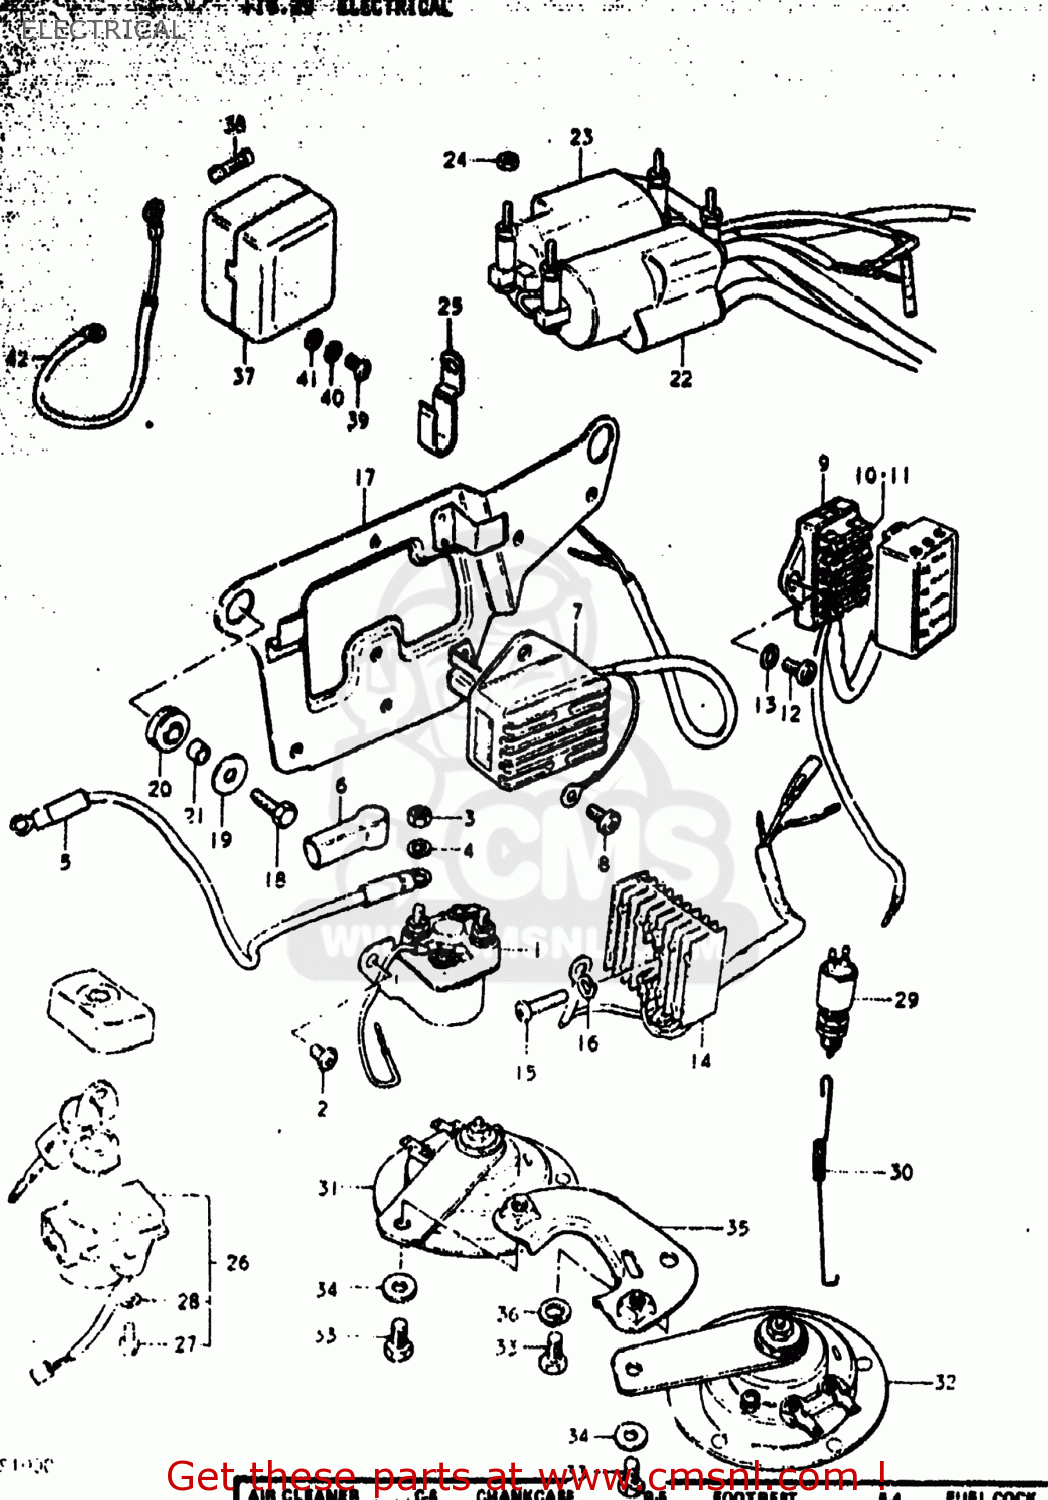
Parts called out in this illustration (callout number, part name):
1	RELAY ASSY,STARTING MOTOR
2	SCREW
3	NUT 6MM
4	LOCK WASHER
5	WIRE,STARTER MOTOR LEAD
6	CAP,STARTER RELAY
7	REGULATOR ASSY,VOLTAGE
8	SCREW
9	BOX ASSEMBLY,FUSE
10	FUSE(10A)
11	FUSE(15A)
12	SCREW 6X12
13	WASHER 6MM
14	RECTIFIER ASSEMBLY
15	SCREW
16	LOCK WASHER
17	HOLDER COMP,ELECTRONIC PARTS
18	BOLT, UPPER
19	WASHER(6,5X22X1.6)
20	CUSHION
21	SPACER(6.2X8.3X5.7)
22	COIL ASSEMBLY,IGNITION
23	COIL ASSEMBLY,IGNITION
24	NUT
25	CLAMP
26	LOCK ASSEMBLY,STEERING
27	BOLT
28	LOCK WASHER
29	SWITCH ASSY,BRAKE LAMP
30	SPRING
31	HORN ASSY
32	HORN ASSEMBLY,HIGH PITCH
33	BOLT 8X12
34	WASHER
35	BRACKET,HORN
36	LOCK WASHER
37	TERMINAL ASSEMBLY,POWER SO
38	FUSE(10A)
39	SCREW
40	LOCK WASHER
41	WASHER
42	WIRE,POWER SOURCE LEAD
43	CAP,IGNITION SWITCH
